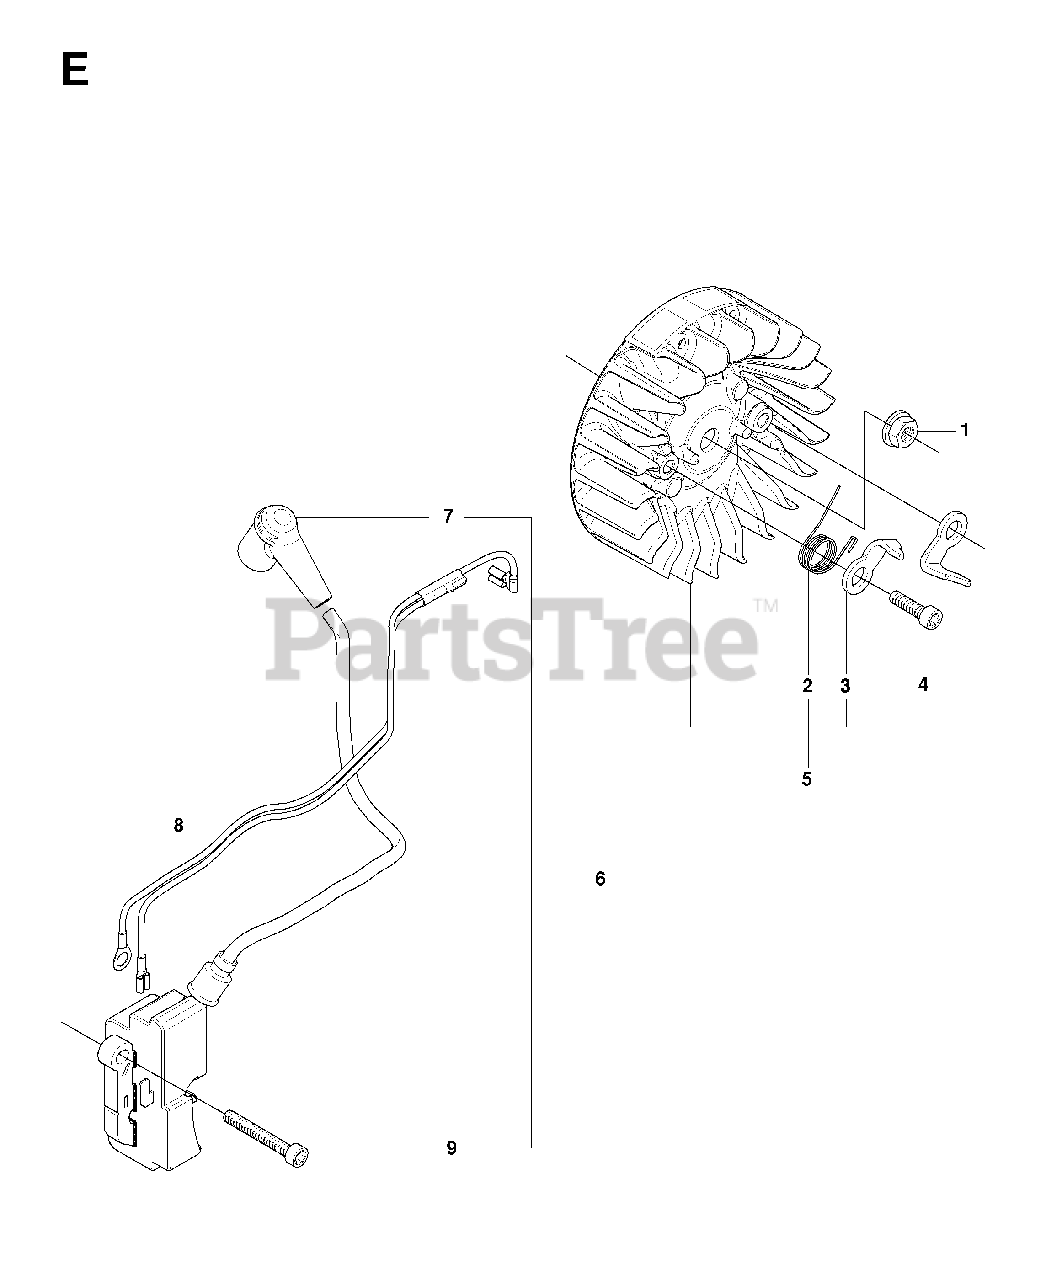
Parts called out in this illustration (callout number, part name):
1	NUT W/ WASHER
2	%SPRING, STARTER CATCH
4	PIN, STARTER CATCH
6	IGNITION MODULE
7	SPARK PLUG CONN. KIT
8	CABLE ASSY
